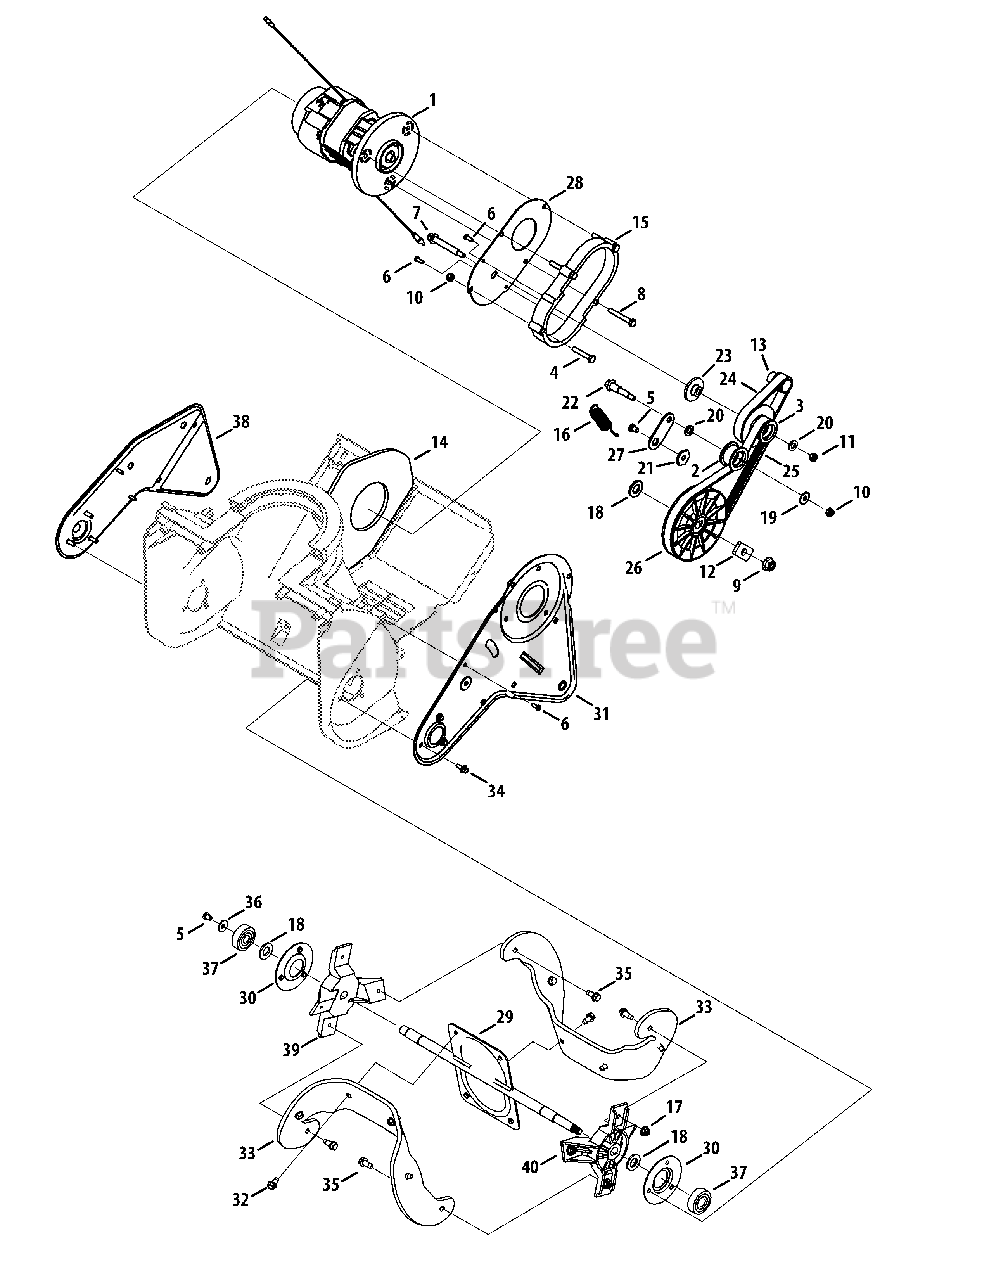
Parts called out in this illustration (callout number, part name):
1	Motor Assembly (Incl. Ref 13)
2	Pulley Assembly, Idler
3	Pulley Assembly
4	Screw, M6-1, 35.00
5	Screw, Hex Screw, M6 x 8mm
6	Screw, Tap, M4.2 x 1.4 x 13
7	Screw, Hex Flange, M8-1.25, 60mm
8	Screw, M6-1, 45.00
9	Nut, Flange Lock, 3/8-16, Nylon
10	Nut, Hex Lock, M6-1
11	Nut, Hex Lock, M8-1.25, Nylon
12	Plate, Drive Pulley
13	Pulley, 5mm, 15 Tooth
14	Gasket, Foam
15	Spacer, Motor Mount
16	Extension Spring, Idler
17	Nut, Flange Lock, 1/4-20, Nylon
18	Washer, Flat, M12
19	Washer, Flat, 6.4 Id x 18 OD
20	Washer, Flat, .320 x .600 x .060
21	Spacer, Shoulder, Hex, M6
22	Screw, Shoulder
23	Spacer, 8.35 x 16 x 11.65
24	Belt, Sync
25	Belt, Poly, 6 Rib
26	Pulley, Auger, 6 Rib
27	Bracket, Idler
28	Plate, Motor Mount
30	Cover, Bearing
31	Outer Frame, LH
32	Screw, Self-tapping, 1/4-20, 0.625
33	Paddle Auger, Rubber
34	Screw, Self-tapping, 1/4-20, 0.500
35	Screw, 1/4-10 x .75
36	Washer, Flat, 6.4 Idx18 OD
37	Bearing, Ball, 12 x 37 x 12
38	Outer Frame, RH
39	Bracket, Paddle, Mount, LH
40	Bracket, Paddle, Mount, RH
